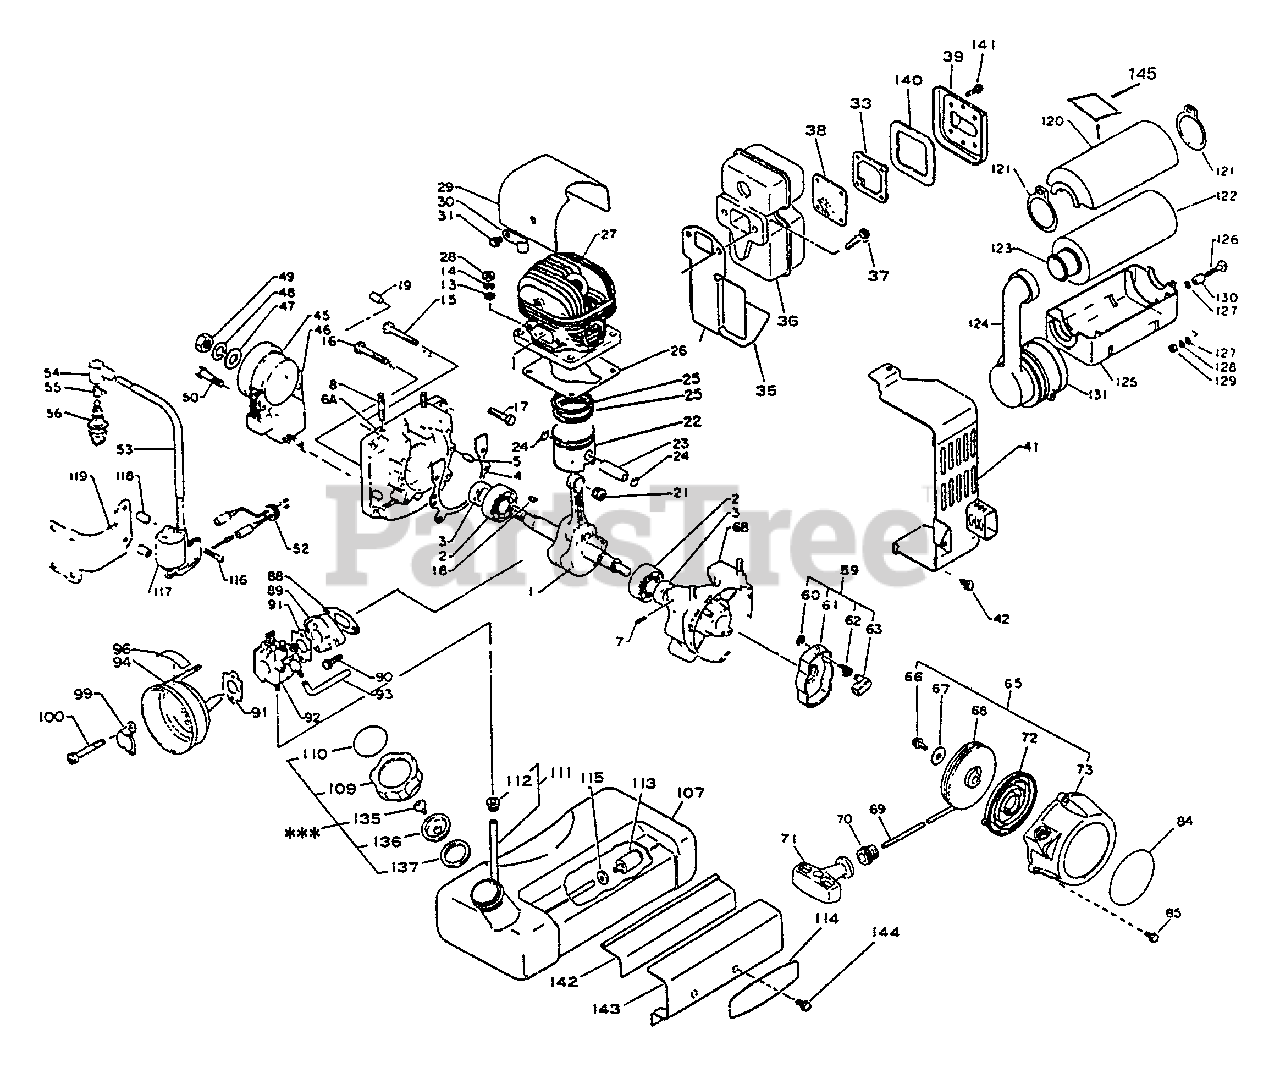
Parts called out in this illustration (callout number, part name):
1	CRANKSHAFT ASSY
2	BEARING, BALL - 6202
3	SEAL, OIL
4	GASKET KIT
5	PIN - LOCATING
6	CRANKCASE KIT
6A	CRANKCASE KIT
7	CONNECTOR
13	WASHER - 6
14	LOCKWASHER - 6
17	BOLT - 6X25
21	BEARING, NEEDLE
22	PISTON
23	PIN, PISTON
24	RING, RETAINING - 8
25	RING, PISTON
26	GASKET, CYLINDER
27	CYLINDER
28	LOCKNUT - 6
29	SHIELD, CYLINDER
31	BOLT - 6X10
33	RETAINER, SCREEN
35	GASKET, EXHAUST
37	SCREW - 6X20
38	SCREEN, SPARK ARRESTOR
39	GUIDE, EXHAUST
41	COVER, EXHAUST
42	SCREW - 5X14
45	FLYWHEEL
46	COIL, IGNITION
48	LOCKWASHER
50	SCREW - 5X25
54	CAP, SPARK PLUG
55	TERMINAL, SPARK PLUG CAP
56	SPARK PLUG -- BM-6A
59	STARTER PAWL ASSY
60	RING, RETAINING - 6
61	CATCHER, PAWL
62	SPRING, RETURN
63	PAWL, STARTER
65	STARTER ASSY
68	REEL, ROPE
69	ROPE, STARTER - 4X880
70	GUIDE, ROPE
71	GRIP, STARTER
72	SPRING, REWIND
73	CASE, STARTER
84	LABEL - ECHO
85	SCREW - 5X16
88	GASKET, INTAKE
89	INSULATOR, INTAKE
90	SCREW - 6X25
91	GASKET, INTAKE
92	CARBURETOR WA-55
93	PIPE - IMPULSE
94	CASE, AIR FILTER
96	LABEL - CHOKE
99	PLATE, PREVENT
100	BOLT
107	TANK, FUEL
109	CAP ASSY
110	LABEL - FUEL MIX
111	PIPE, FUEL - SPIRAL
113	FILTER, FUEL
114	LABEL - ECHO
115	WASHER - 5
116	SCREW - 4X25
117	COIL, IGNITION
120	COVER, AIR FILTER
122	FILTER, AIR
123	FILTER, AIR
124	ADAPTOR, INTAKE
125	CASE, AIR FILTER
126	BOLT
127	WASHER - 5
128	LOCKWASHER - 5
131	CLAMP
136	HOLDER, VENT
137	GASKET, CAP
140	GASKET, EXHAUST
141	SCREW - 4X14
142	CUSHION, FUEL TANK
143	BRACKET, FUEL TANK
144	SCREW - 5X10
145	LABEL - CAUTION
